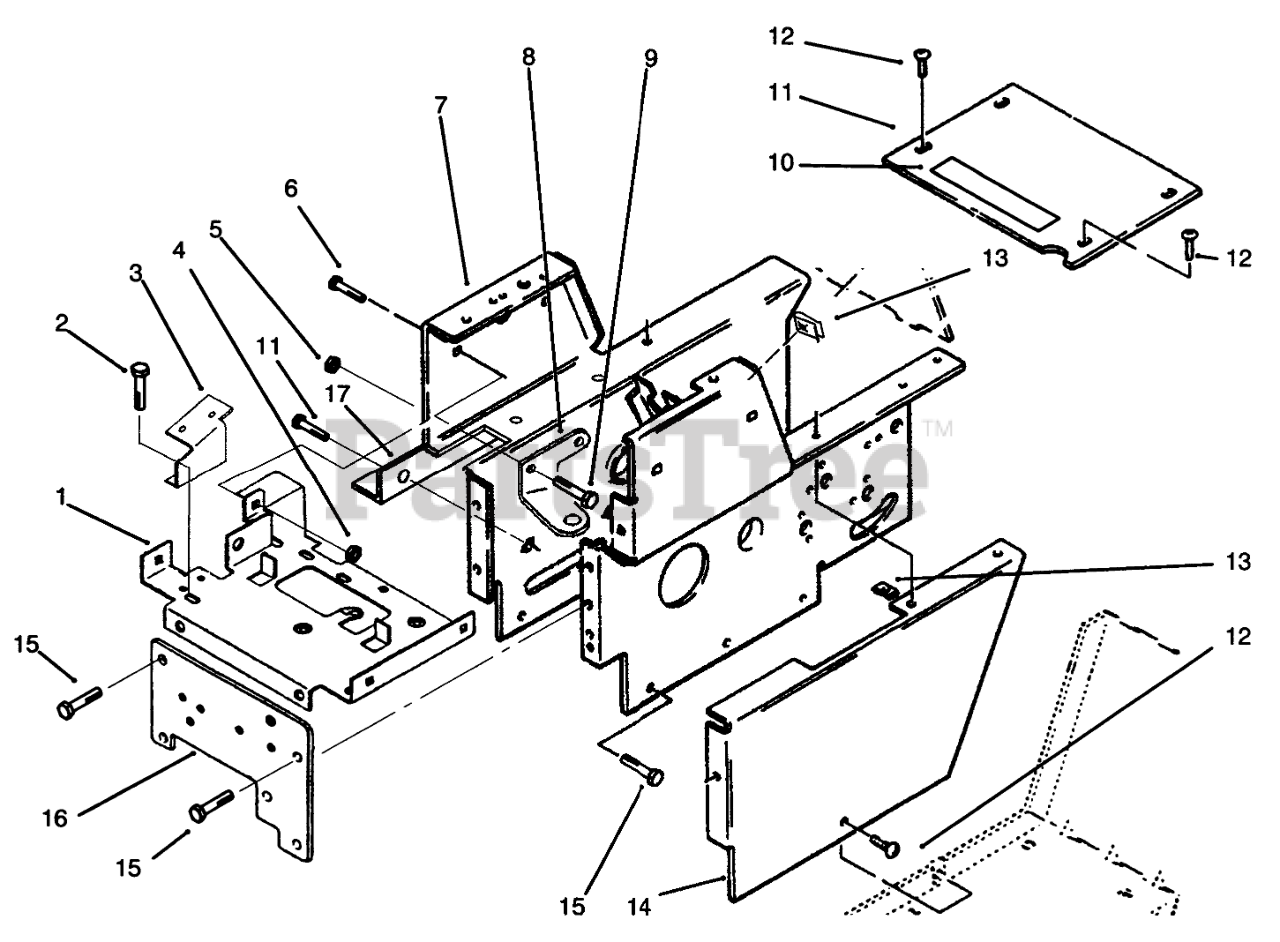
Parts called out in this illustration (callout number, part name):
1	SUPORT-BATERYB
2	SCREW-HWH
3	BRACKET-SWITCH
4	Nut
5	NUT-LOCK, NI
6	BOLT CARR. 5/16X1/2 BK
7	Hoodstand
8	Bracket-Control
9	SCREW-HH
10	DECAL-DANGER
11	Plate-Shift Cover (Incl. Ref. #10)
12	Screw
14	Cover-Side LH
15	Bolt
16	Front Plate
17	ANGL-BLT GURDB
